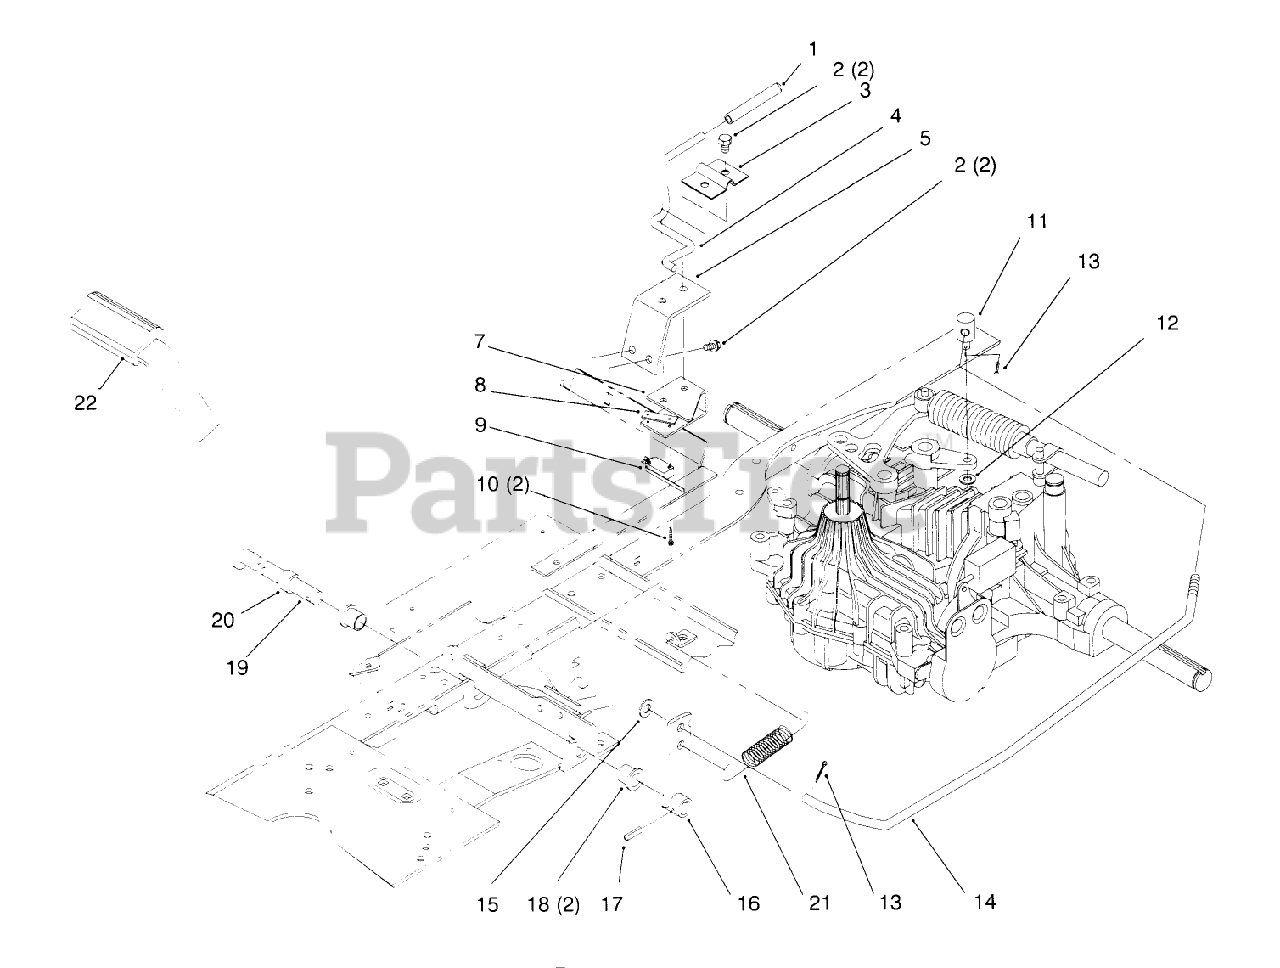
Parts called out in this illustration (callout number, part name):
1	GRIP - PARKING BRAKE
2	SCREW-HWHTF
3	BRACKET-PARKING BRAKE
4	ROD - PARKING BRAKE
5	SUPPORT-P. BRAKE
7	BRACKET-BRAKE SWITCH
8	NUT-SPEED
9	SWITCH-MICRO
11	TRUNNION - BRAKE
12	WASHER-PLAIN
13	PIN-COTTER
15	WASHER-FLAT
17	PIN-SPRING
18	BUSHING-FLANGE
20	SPACER-BRAKE
22	PAD-PEDAL
